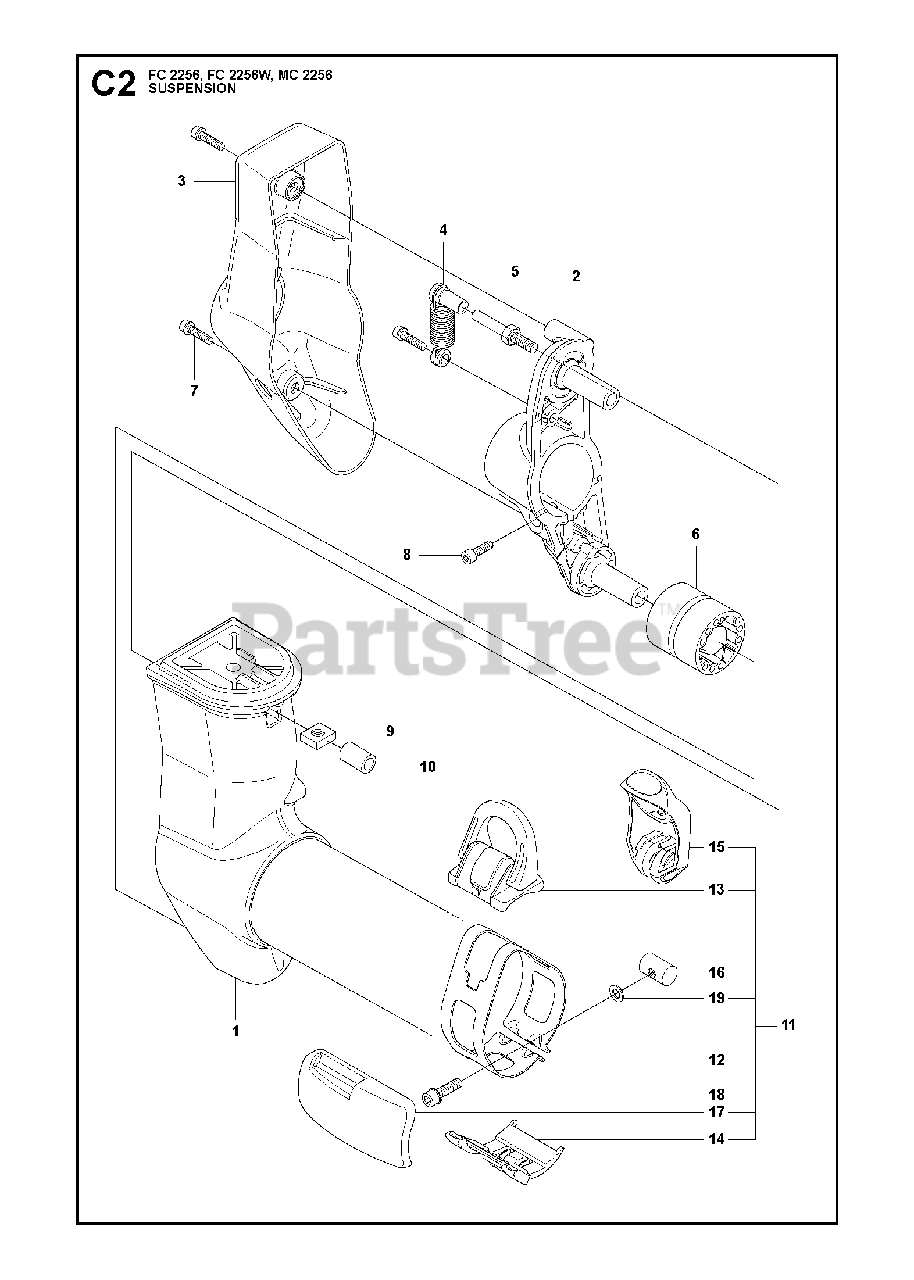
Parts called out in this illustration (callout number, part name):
1	SUSPENSION
5	PARALLEL PIN
6	ANTIVIBE ELEMENT
7	SCREW IHSCFM
12	BAND
16	NUT
18	SCREW
19	WASHER 5.3X12
